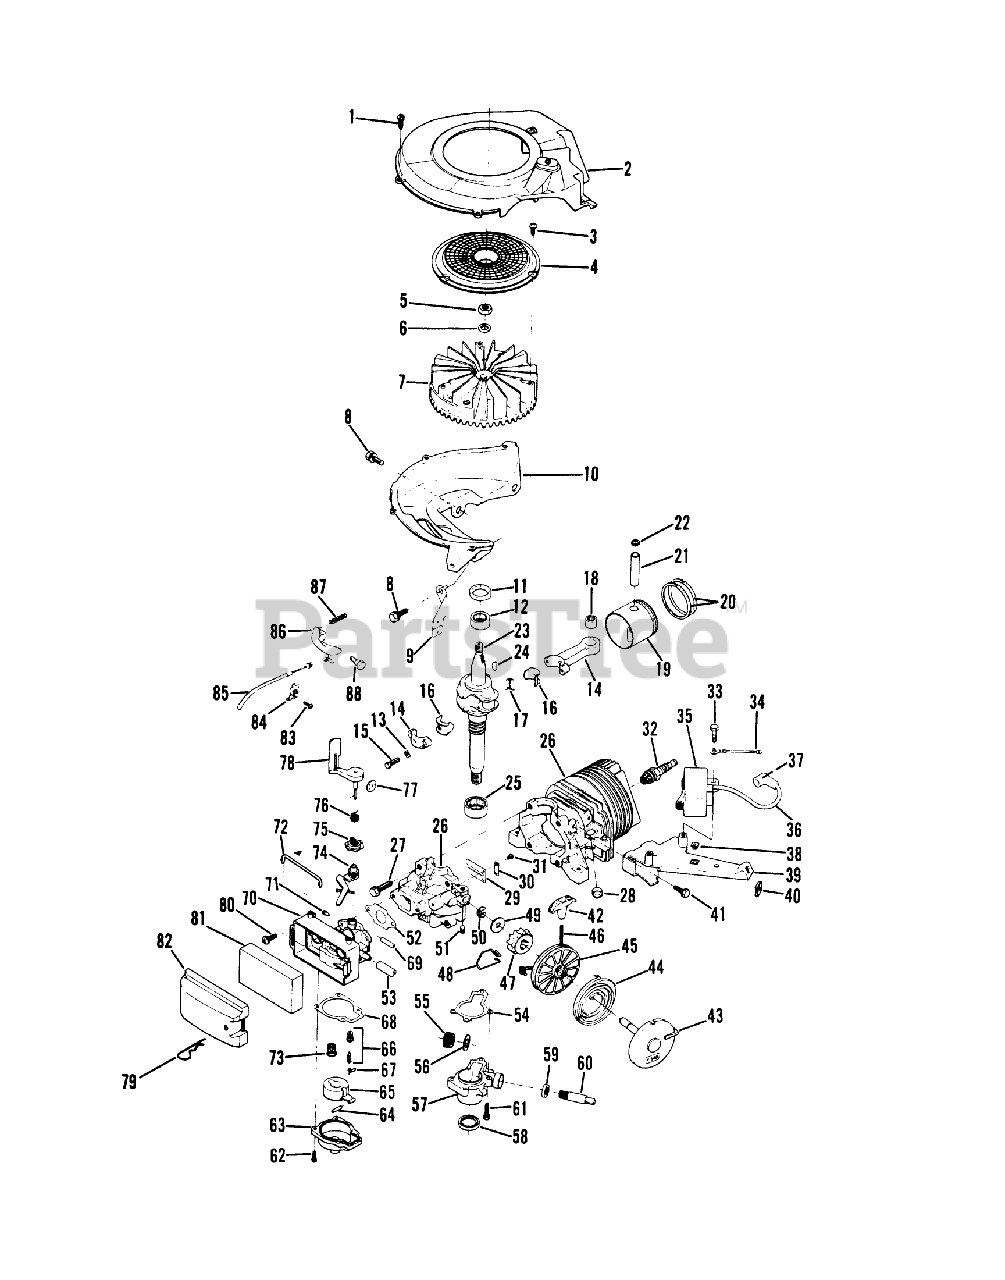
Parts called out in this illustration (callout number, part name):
1	SCREW S
2	AIR BAF&EYELET S
3	SCREW F
5	NUT
8	SCREW-SEMS
12	BEARING V
15	SCREW
16	LINER ASM
18	BEARING AY F
22	RING-RETAINING
24	KEY
25	BEARING S
27	SCREW S
28	PLUG-CORE VF
30	PLATE-BACKUP, REED
36	HT LEAD&COVER XEV
38	NUT-CLIP
40	NUT - SPEED S
42	HANDLE STARTER S
44	SPRING S
48	SPRING F
49	WASHER S
51	SET SCREW
52	GASKET CARB S
54	GASKET S
55	GEAR, DR SHAFT S
56	THRUST WASHER
59	SEAL S
62	SCREW-HH
69	TUBING PRIMER S
70	Carburetor Body
71	F-SCREW CARB
72	RETAINER
74	LEVER
75	ADJUSTMENT COLLAR
76	SPRING
77	DISC S
79	HAIR PIN
80	SCREW
84	CLIP S
86	LEVER LOCKOUT S
88	BOLT S
